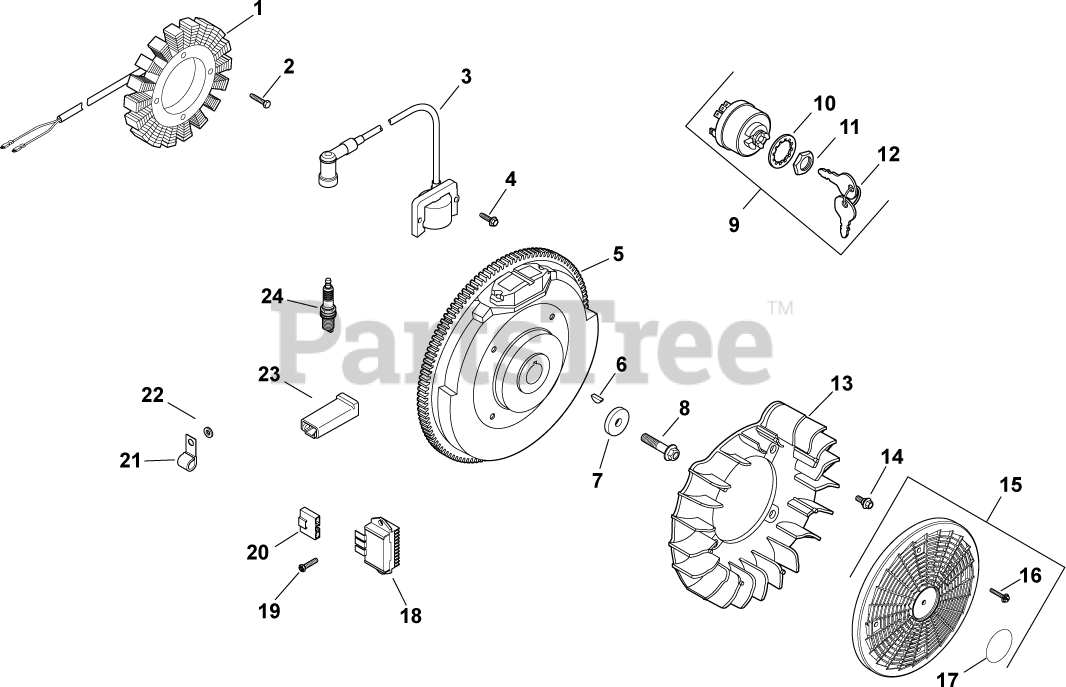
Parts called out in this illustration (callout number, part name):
1	KIT, 15 / 20 AMP STATOR
2	SCREW, M5X0.8X25 - (#25086402S)
3	KIT, MODULE IGNTN (CDI FIXED)
4	SCREW, FLG THD FRM M5X.8X20-(#25086399S)
5	FLYWHEEL ASSEMBLY
6	KEY, 3/16" X 5/8"
7	WASHER, FLAT 13/32"
8	SCREW, FLG M10X1.5X45 - (#25086361S)
9	SWITCH ASSY, KEY (KM)-USE 25 099 32-S
10	WASHER, INTERNAL TOOTH
11	NUT, KEY SWITCH
12	KEY, SET -USE 48 340 01-S
13	FAN USE 24 755 253-S
14	BOLT, SHOULDER
15	KIT, GRASS SCREEN
16	SCREW, FLG SEMS M4X.7X25
17	DECAL, GRASS SCREEN USE 24 113 499-S
18	REG/RECTIFIER (20/25 AMP)-USE 25 403 20-
19	SCREW, HEX FLANGE HI-LO
20	CONNECTOR, BODY (KM)-USE 25 155 41-S
21	CLIP, CABLE
22	WASHER, FLAT 1/4" (O.D. 1/2")
23	CONNECTOR (1 CONTACT)
24	PLUG, SPARK (PRO SERIES)
